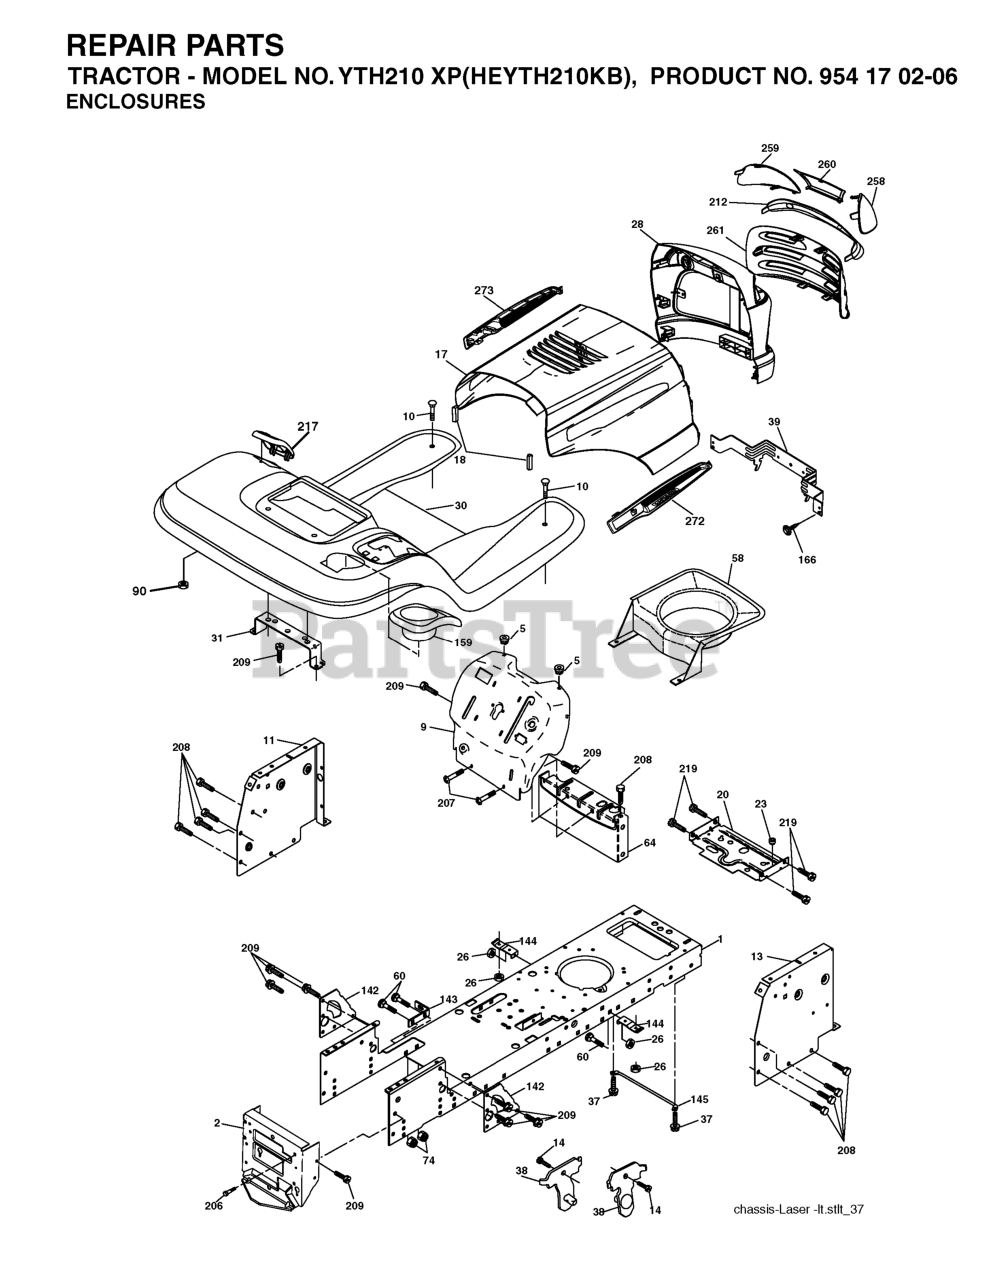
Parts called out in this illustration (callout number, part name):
1	CHASSIS STAMPING
2	DRAWBAR, 12GA
5	BUMPER.RUBBER.HOOD
10	BOLT D
11	PANEL.DASH.LH.LTX
13	PANEL ASM, DASH RH
17	VENT.HOOD.LASER.III
18	BUMPER.HOOD.LARGE.1.75"
20	PLATE MTG.BATTERY/FUEL TANK
23	BUSHING.SNAP.NYL.BLK.
26	NUT
30	FENDER
31	BRACKET.SUPPORT.FENDER
37	Screw 5/16-18 x 1/2 Hex, Self Tapping 5/16-18 x 1/2
38	BRACKET.ASM.PIVOT.MOWER.REAR
39	BRACKET PIVOT LASER
60	Bolt - Rd. Hd. Sq. Neckiage 3/8 16 x 3/4
64	DASH LOWER
90	NUT.PUSH.3/16
142	PLATE REINFORCEMENT
143	BRACKET, SWAYBAR CHASSIS
144	BRKT, FOOT REST
145	ROD PIVOT CHASSIS/HOOD
159	GREY CUP HOLDER
166	SCREW
206	SHOULDER BOLT 5/16-18TT
207	SCREW, 5/16-18 X 1/2
208	SCREW 3/8-16X1/2
209	SCREW, 3/8-16X3/4
212	INSERT.LENS.REFLECTIVE
217	CONSOLE FUEL WINDOW
219	SCREW
258	LENS LH
259	LENS LH
260	COVER.LENS.HUSQ.LASER
272	VENT.HOOD.LASER.
273	VENT.HOOD.LASER.
